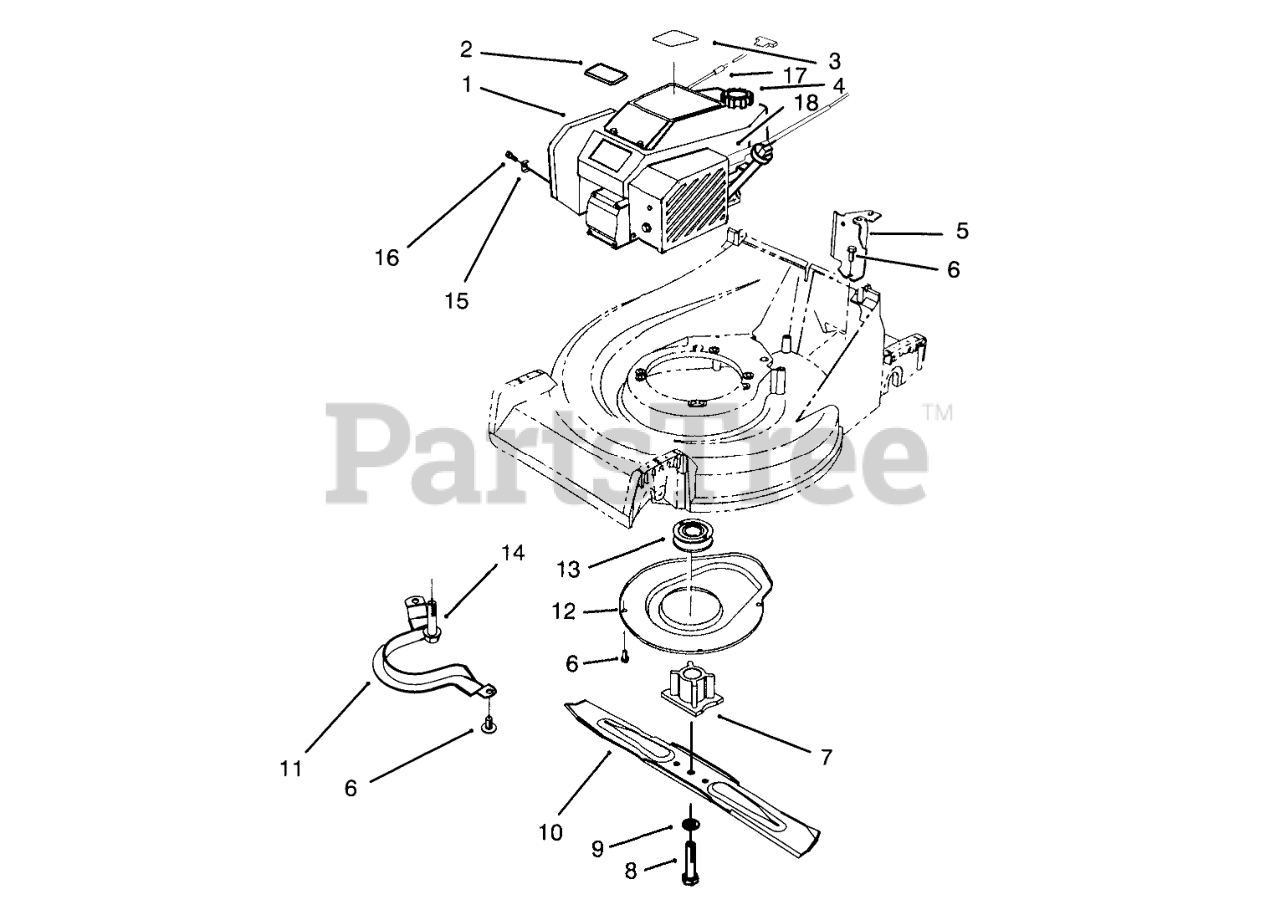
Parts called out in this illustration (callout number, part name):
1	Engine
2	PLATE-LOGO
3	DECAL - ENGINE
4	GAS CAP ASM
5	Bracket-Cable Support
6	SCREW-HWHTF
7	BLADE RETAINER
8	SCREW-BLADE
9	WASHER-LOCK
10	Key
11	Guide-Belt
12	Cover
13	PULLEY-DRIVE, ZONE START
14	SCREW-HWH
15	CLAMP-CASING
16	CLAMP SCREW F/W ENGINE
17	STOP-ROPE
18	BRAKE COVER-P/W ENGINE
